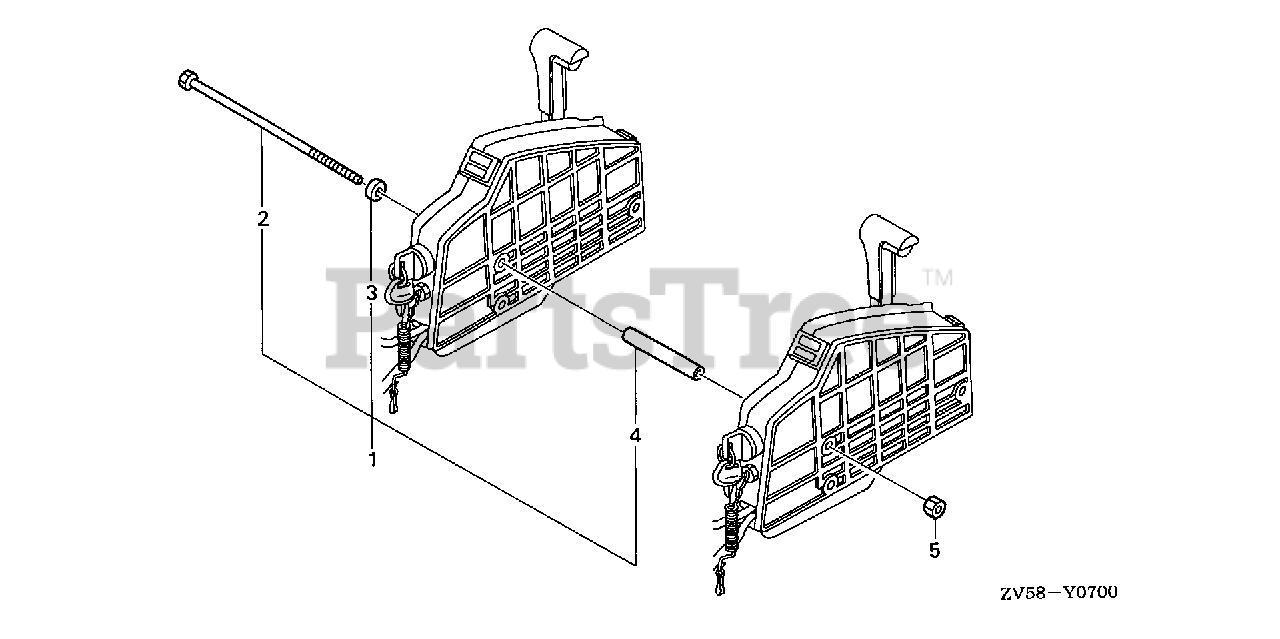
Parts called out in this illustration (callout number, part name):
1	BOLT KIT, SIDE REMOTE CONTROL
2	BOLT, SPECIAL (6X220)
3	COLLAR, DISTANCE (A)
4	COLLAR, DISTANCE (B)
5	NUT, HEX. (6MM)
